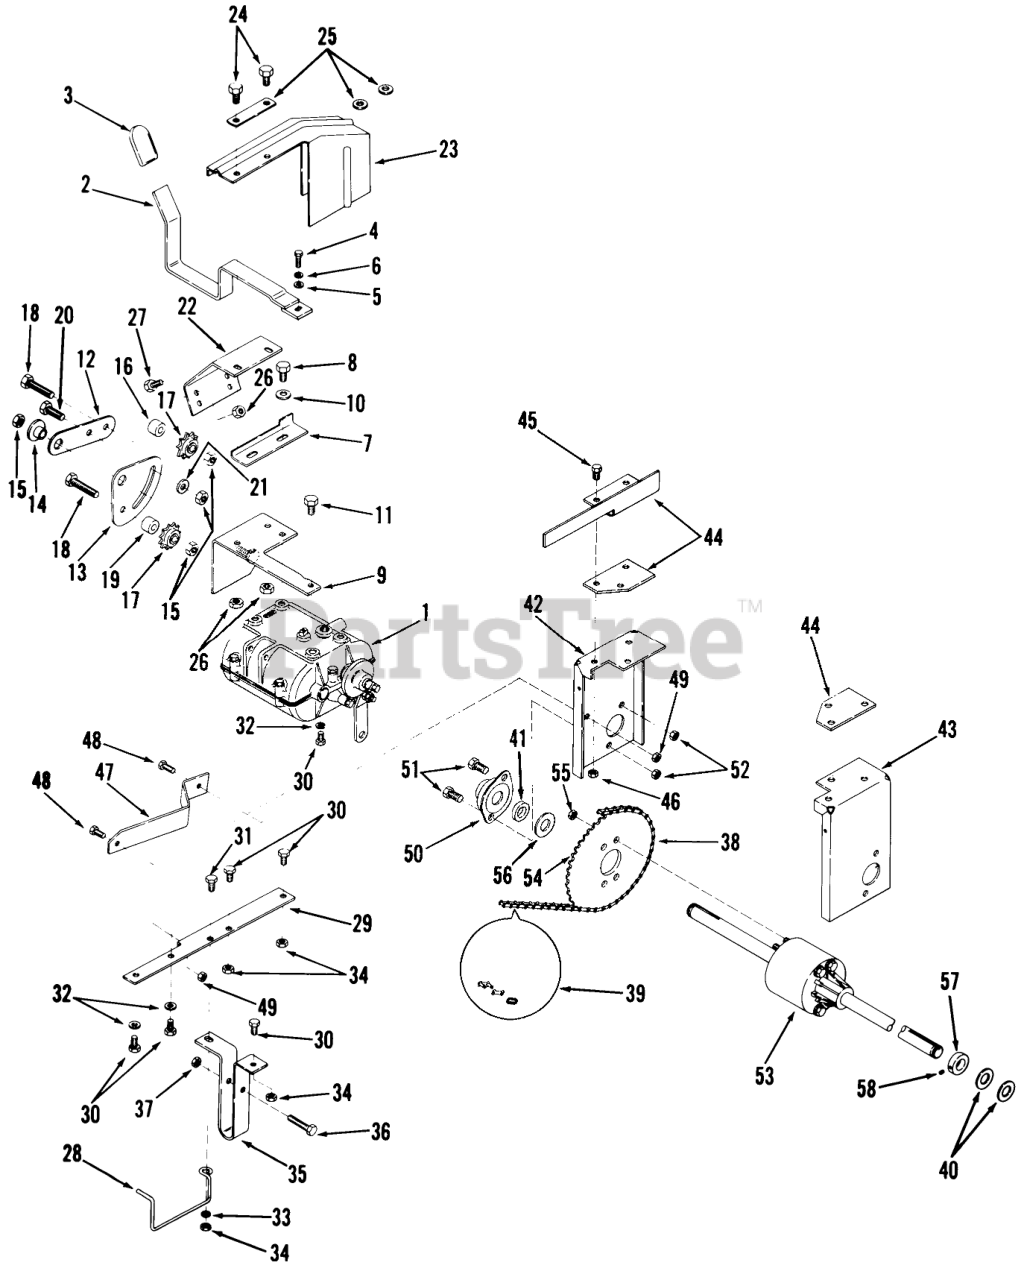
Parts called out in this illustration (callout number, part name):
30	Bolt
31	Bolt
32	Lockwasher
33	Washer
34	Nut
35	Mower Guide
36	Bolt
37	Nut
38	Chain #41,1/2 in. Pitch,86 Pitches
39	Master Link-Service Only
40	WASHER
41	Spacer
42	Rear Axle Bracket RH
43	Rear Axle Bracket LH
44	Plate Rear Axle Support
44	LOCATOR-BATTERY
45	Bolt
46	Nut
47	Brace-Rear Axle Bracket RH
48	Bolt
49	Nut
50	BEARING-SIDE FLANGE
51	Bolt
52	Nut
53	Differential-Peerless Mod 167A
54	SPROCKET
55	Nut
56	WASHER
57	Collar
58	SCREW-SET
